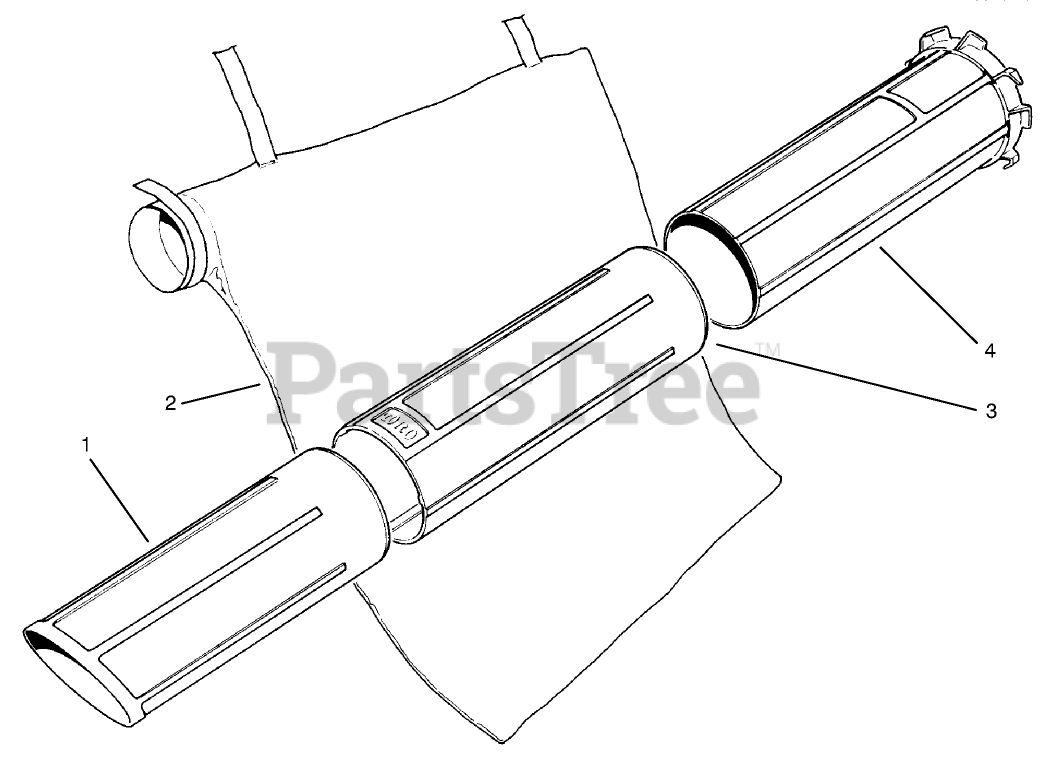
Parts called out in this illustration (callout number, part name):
1	LOWER VAC TUBE
2	VACUUM BAG
3	MIDDLE VAC TUBE
4	UPPER VAC TUBE
